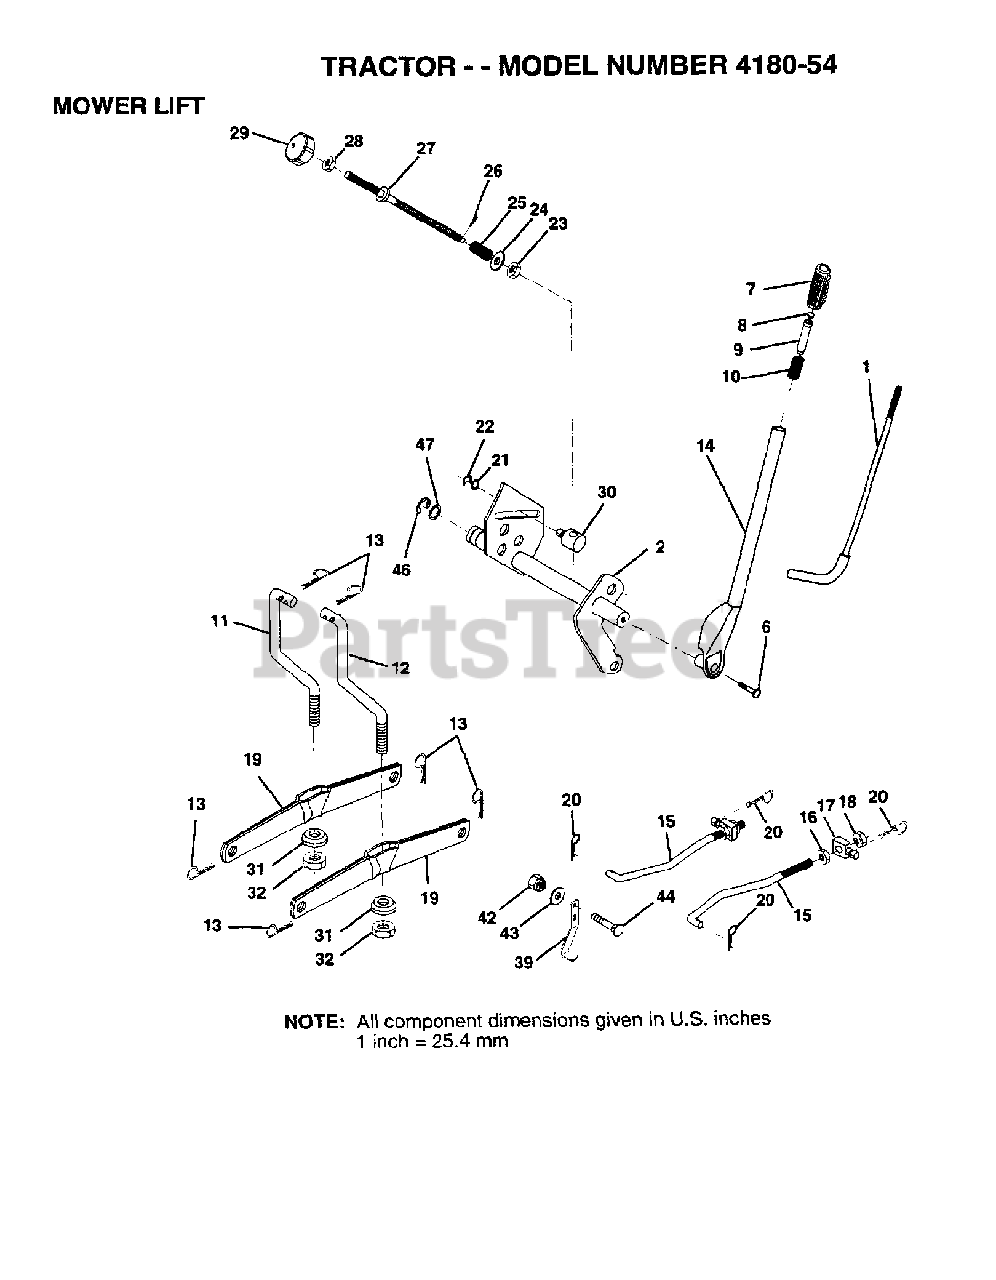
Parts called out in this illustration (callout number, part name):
1	LEVER ROD LT
6	Hex Bolt
7	GRIP
8	PLUNGER BUT KIT
9	PLUNGER BUT KIT
11	LIFT LINK LH
12	LIFT LINK RH
13	RETAINER SPRING
14	LIFT LEVER KIT
15	FRONT LINK
16	NUT.HEX.JAM.1/2-13
18	NUT.LK.W/WSH.1/2.
19	ARM.REAR.SUSPENSION
20	SPRING RETAINER
21	WASHER
22	KLIP RING
24	WASHER
25	SPRING.COMP.INF.H
27	ROD.LIFT.ADJUSTABLE
28	NUT
29	KNOB INF 3/8-16
30	TRUNION LT
32	NUT CROWNLOCK 3/8-24
39	MOWER STOP
42	LOCKNUT
43	WASHER GT
